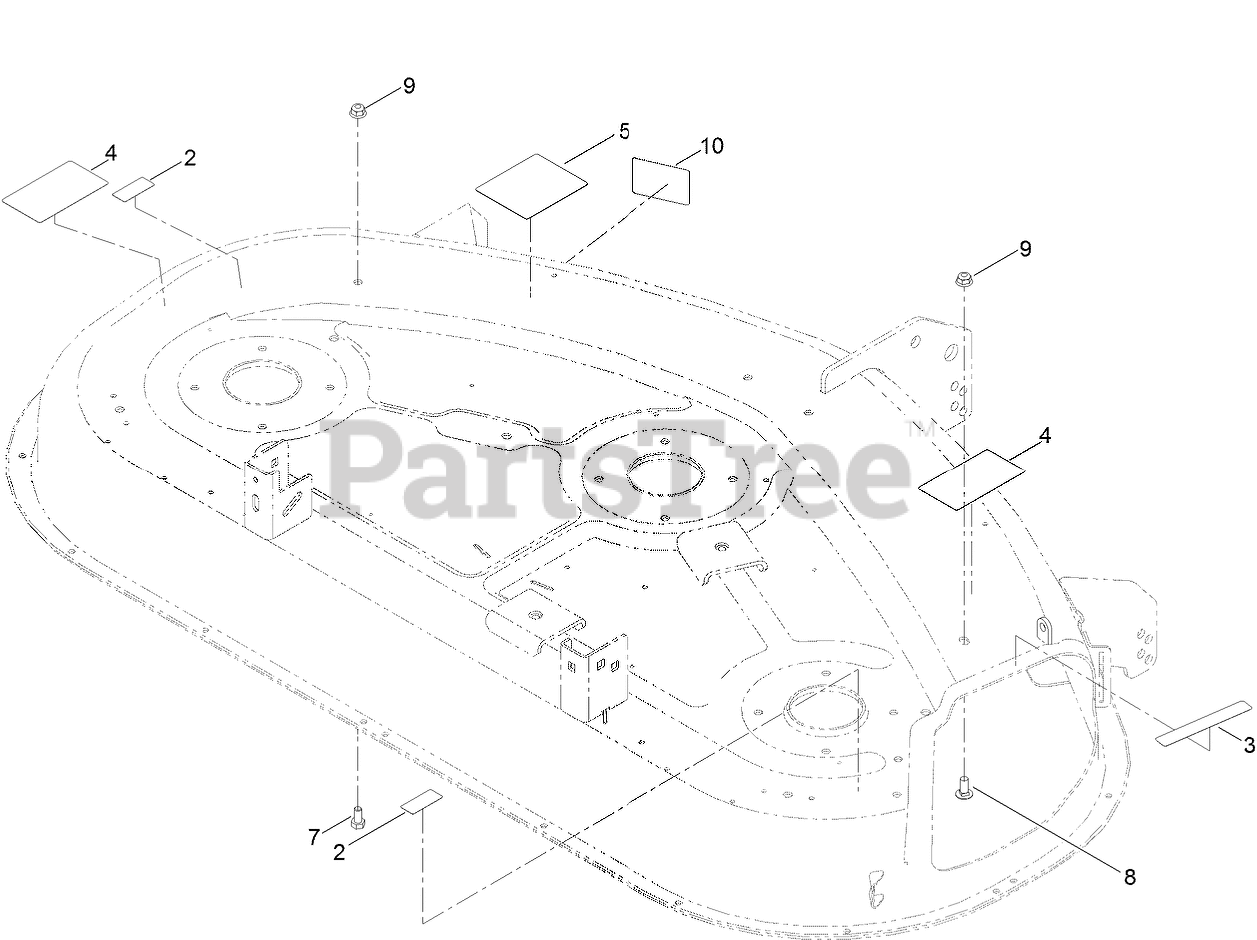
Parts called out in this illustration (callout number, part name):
2	DECAL-DANGER
3	DECAL-DANGER
4	DECAL-DANGER
5	DECAL-ROUTING, BELT
7	SCREW-HH
8	SCREW-CARR
9	NUT-HF, NI
10	DECAL-SCALP, ANTI
